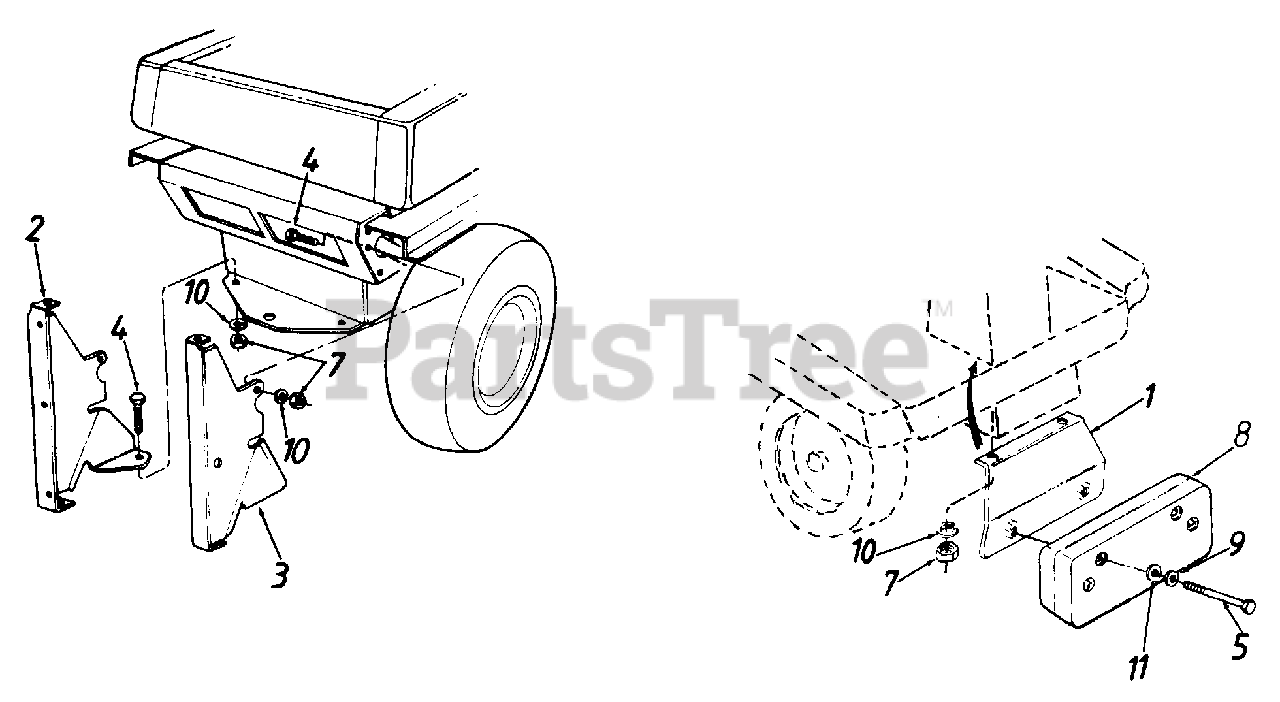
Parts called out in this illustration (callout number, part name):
1	Counterweight Support Brkt.
2	N Catcher Support Brkt. R.H.
3	N Catcher Support Brkt. L.H.
4	Hex Bolt 5/16-18 x l.On Lg. 4
5	Hex Bolt 3/8-16 x 4.5" Lg. 2
7	Hex Nut 5/16-18 Thd. - 0 0 6
8	Front Counterweight
9	Bell-Wash. 3/8" I.D. - 2
10	L-Wash. 5/16" I.D. -6
11	Fl-Wash. 390n I.D. x 1.12" O.D. 2
